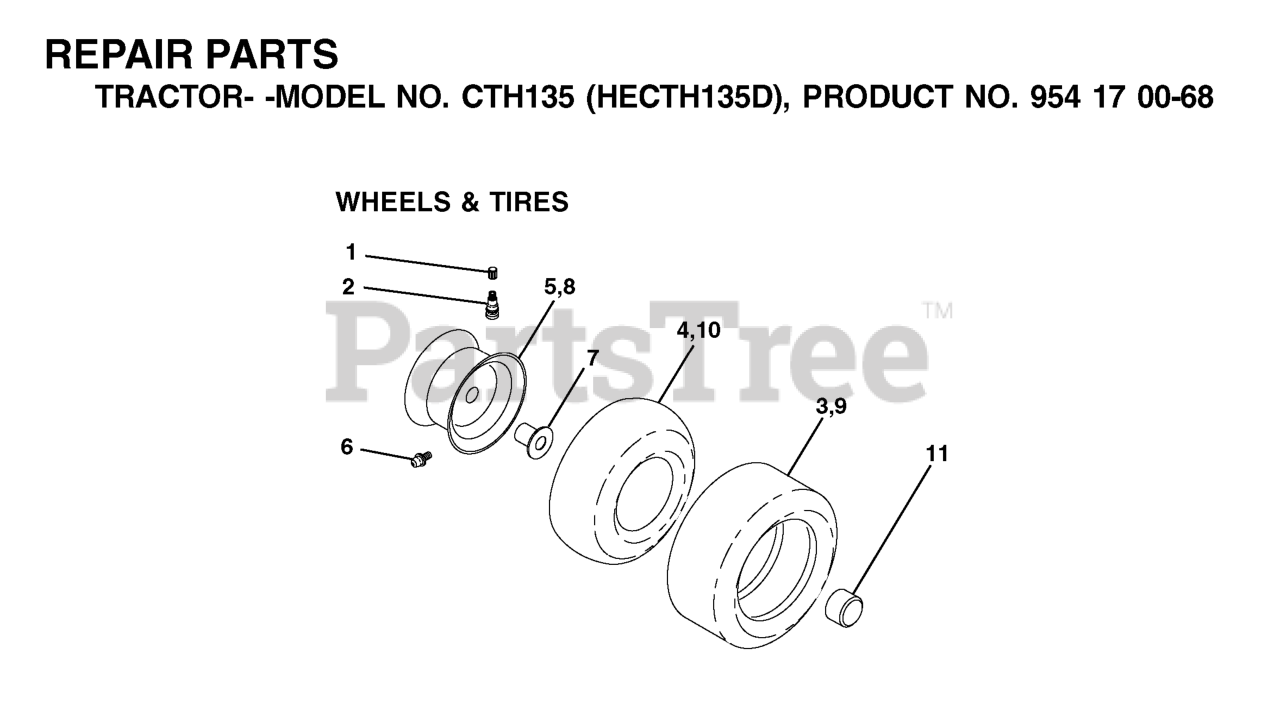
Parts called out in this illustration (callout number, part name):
2	VALVE STEM LT
3	TIRE HEAVY DUTY
4	TUBE.5.3/4.5/6
5	RIM ASM 6" FRONT SILVER
6	FITTING LT
7	BEARING T
8	RIM ASM 8" REAR SILVER
9	TIRE.20X8-8.TURF.SAVER
10	TUBE
11	CAP, AXLE BLK
